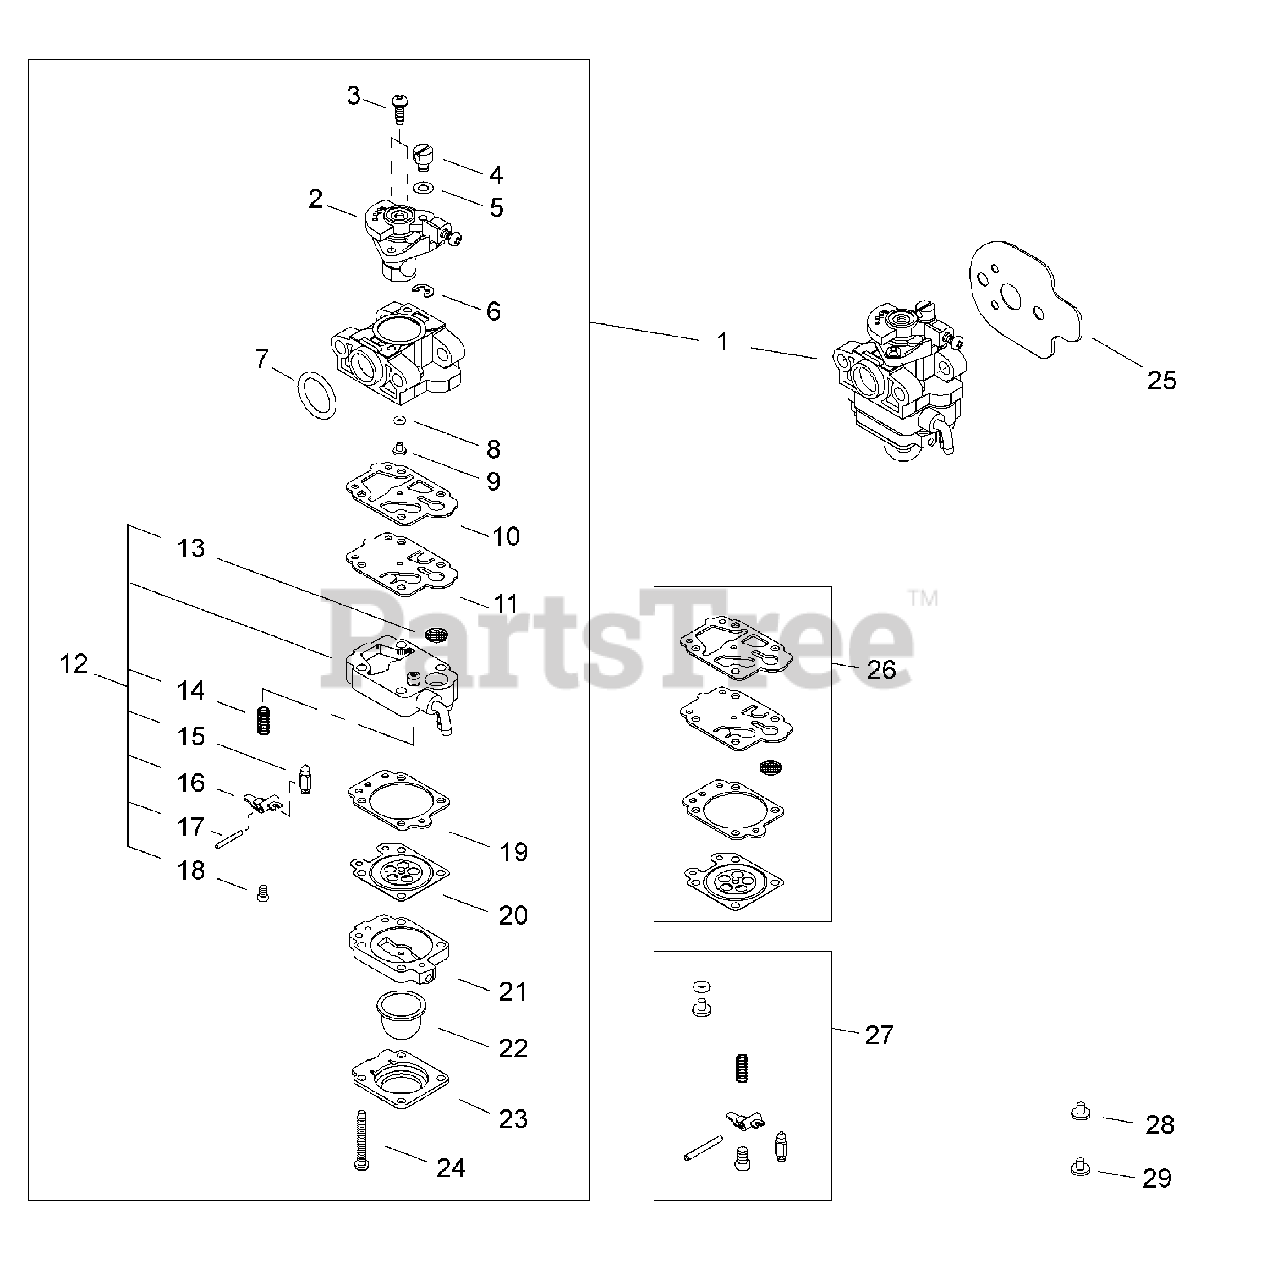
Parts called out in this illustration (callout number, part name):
1	CARBURETOR
2	VALVE ASSY, THROTTLE
3	SCREW, THROTTLE COLLAR
4	SWIVEL
5	WASHER
6	E-RING
7	O-RING 15
8	O-RING
9	JET, MAIN
10	GASKET, PUMP
11	DIAPHRAGM, PUMP
12	BODY ASSY, PUMP
13	SCREEN, FUEL INLET
14	SPRING, METERING LEVER
15	VALVE, INLET NEEDLE
16	LEVER, METERING
17	PIN, METERING LEVER
18	SCREW
19	GASKET, METERING DIAPHRAGM
20	DIAPHRAGM, METERING
21	BODY ASSY, PURGE
22	BULB, PURGE
23	RETAINER, PURGE BULB
24	SCREW
25	GASKET, INTAKE
26	GASKET / DIAPHRAGM KIT
27	VALVE KIT, INLET NEEDLE
28	JET, MAIN #40
29	JET, MAIN #39
